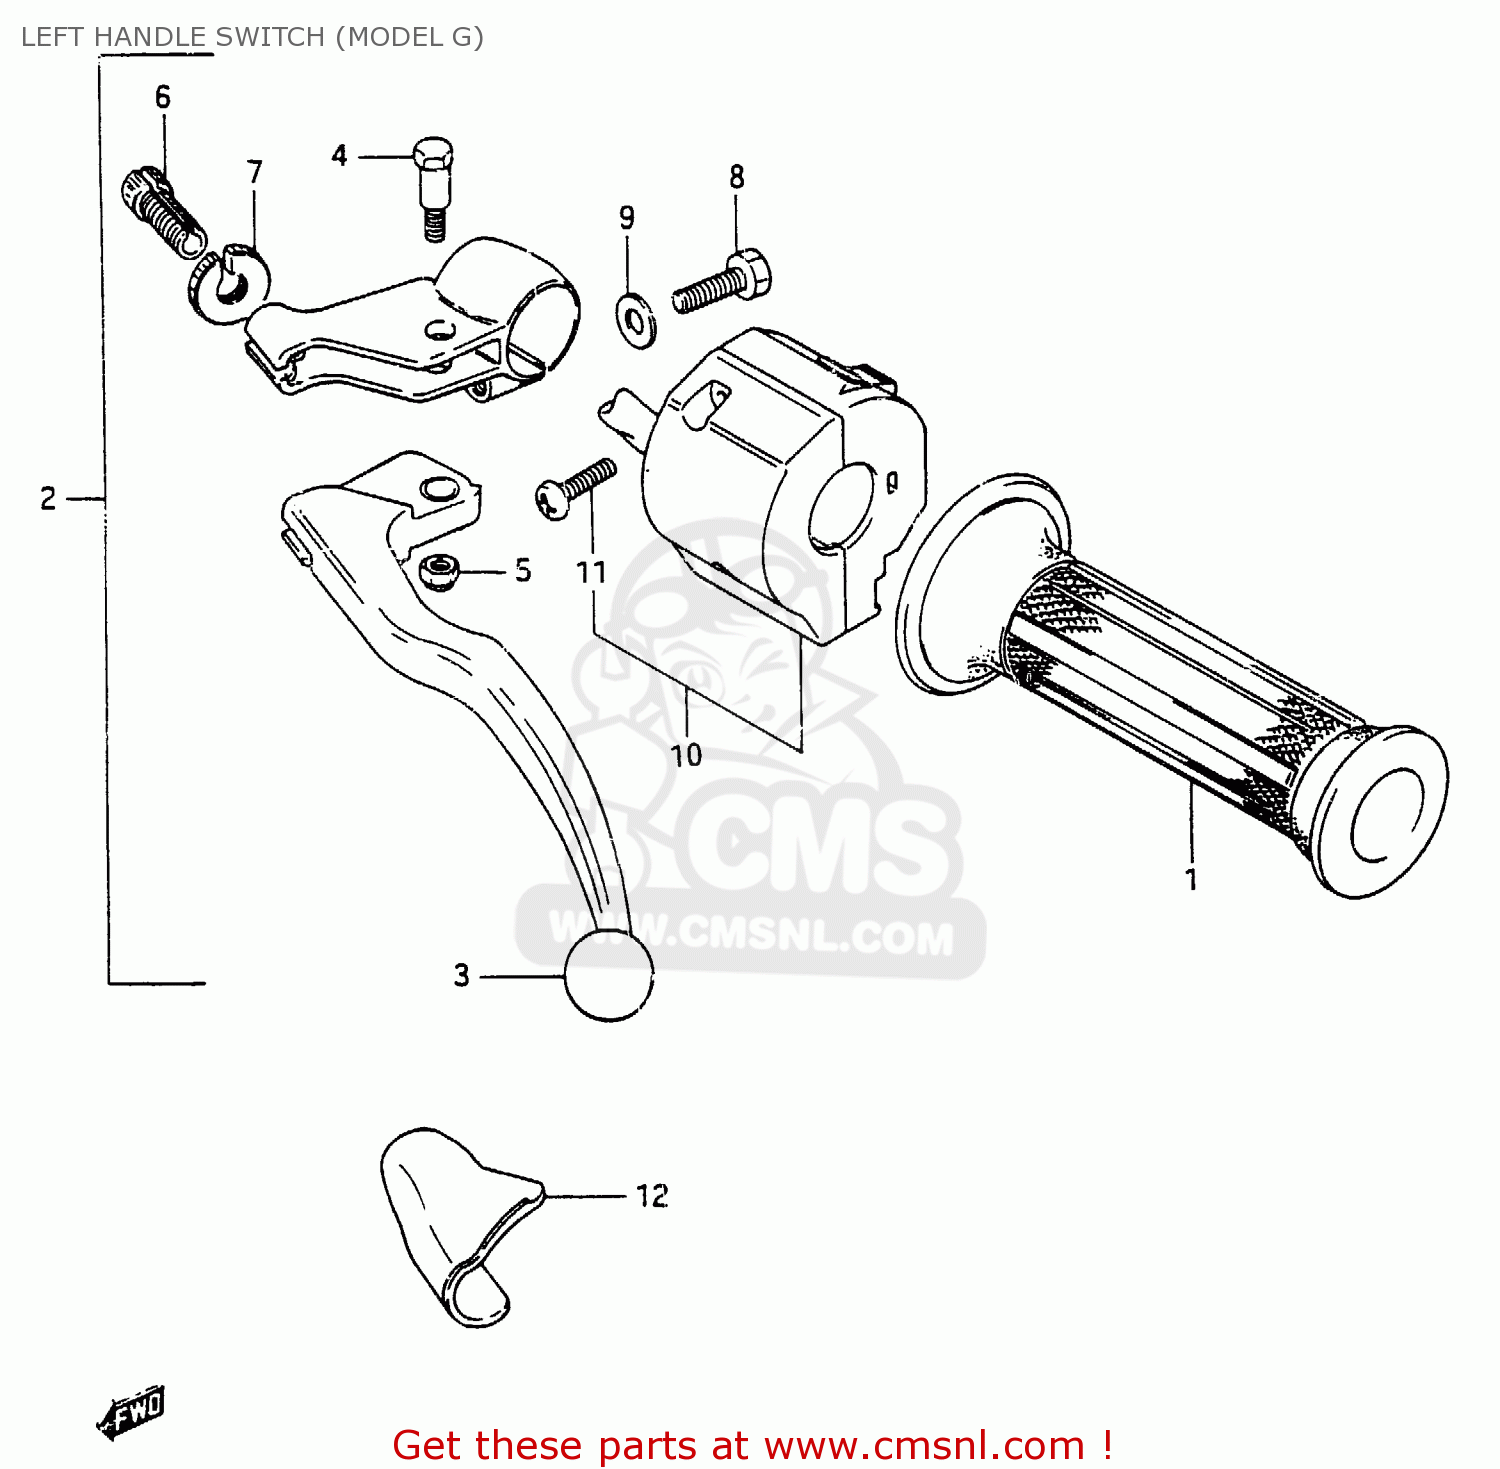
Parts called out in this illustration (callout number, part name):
1	GRIP,L
2	LEVER ASSY, CLUTCH
3	LEVER,CLUTCH
4	BOLT,LEVER PIVOT
5	NUT
6	ADJUSTER,CABLE
7	NUT,CABLE ADJUSTER LOCK
8	BOLT
9	WASHER
10	SWITCH ASSY, HANDLE LH
11	SCREW 5X20
12	COVER,CLUTCH LEVER
